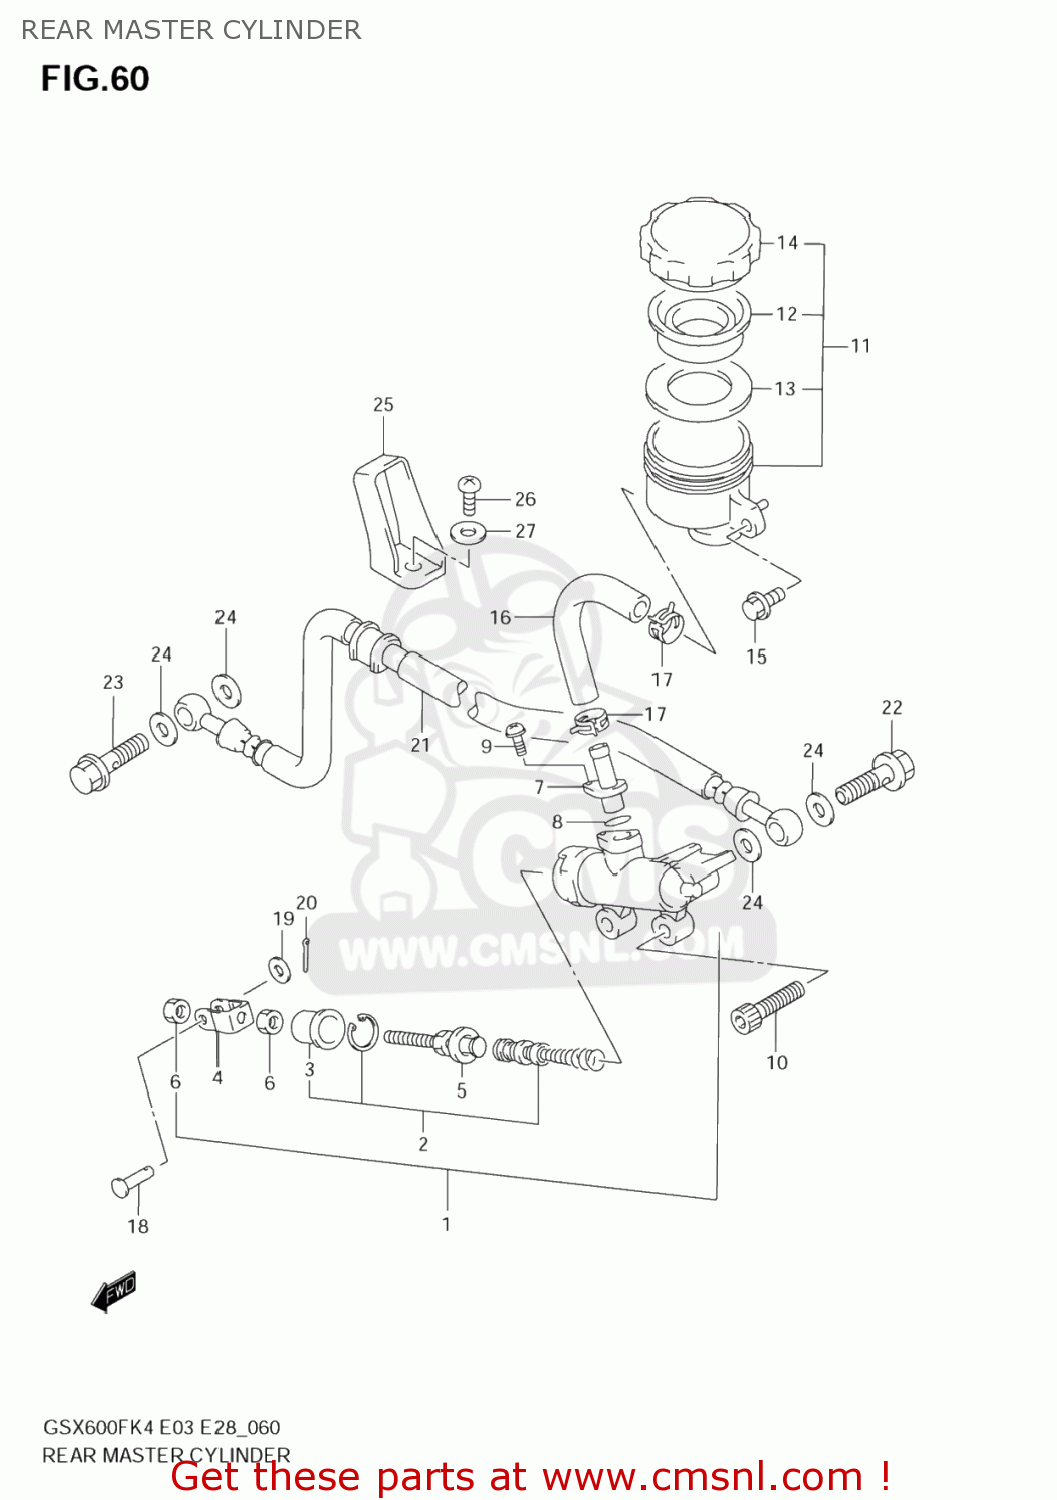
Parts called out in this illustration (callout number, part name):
1	CYLINDER ASSY,RR MASTER
2	PISTON/CUP SET
3	BOOT
4	YOKE
5	ROD,PUSH
6	NUT
7	CONNECTOR
8	O RING
9	SCREW
10	BOLT(6X16)
11	TANK ASSY,RR RESERVOIR
12	DIAPHRAGM
13	PLATE,DIAPHRAGM
14	CAP
15	BOLT
16	HOSE,RESERVOIR TANK
17	CLIP
18	PIN
19	WASHER
20	PIN
21	HOSE COMP,REAR BRAKE
22	BOLT UNION
23	BOLT UNION
24	WASHER(10X15X1.5)
25	GUIDE,RR BRAKE HOSE
26	SCREW
27	WASHER
